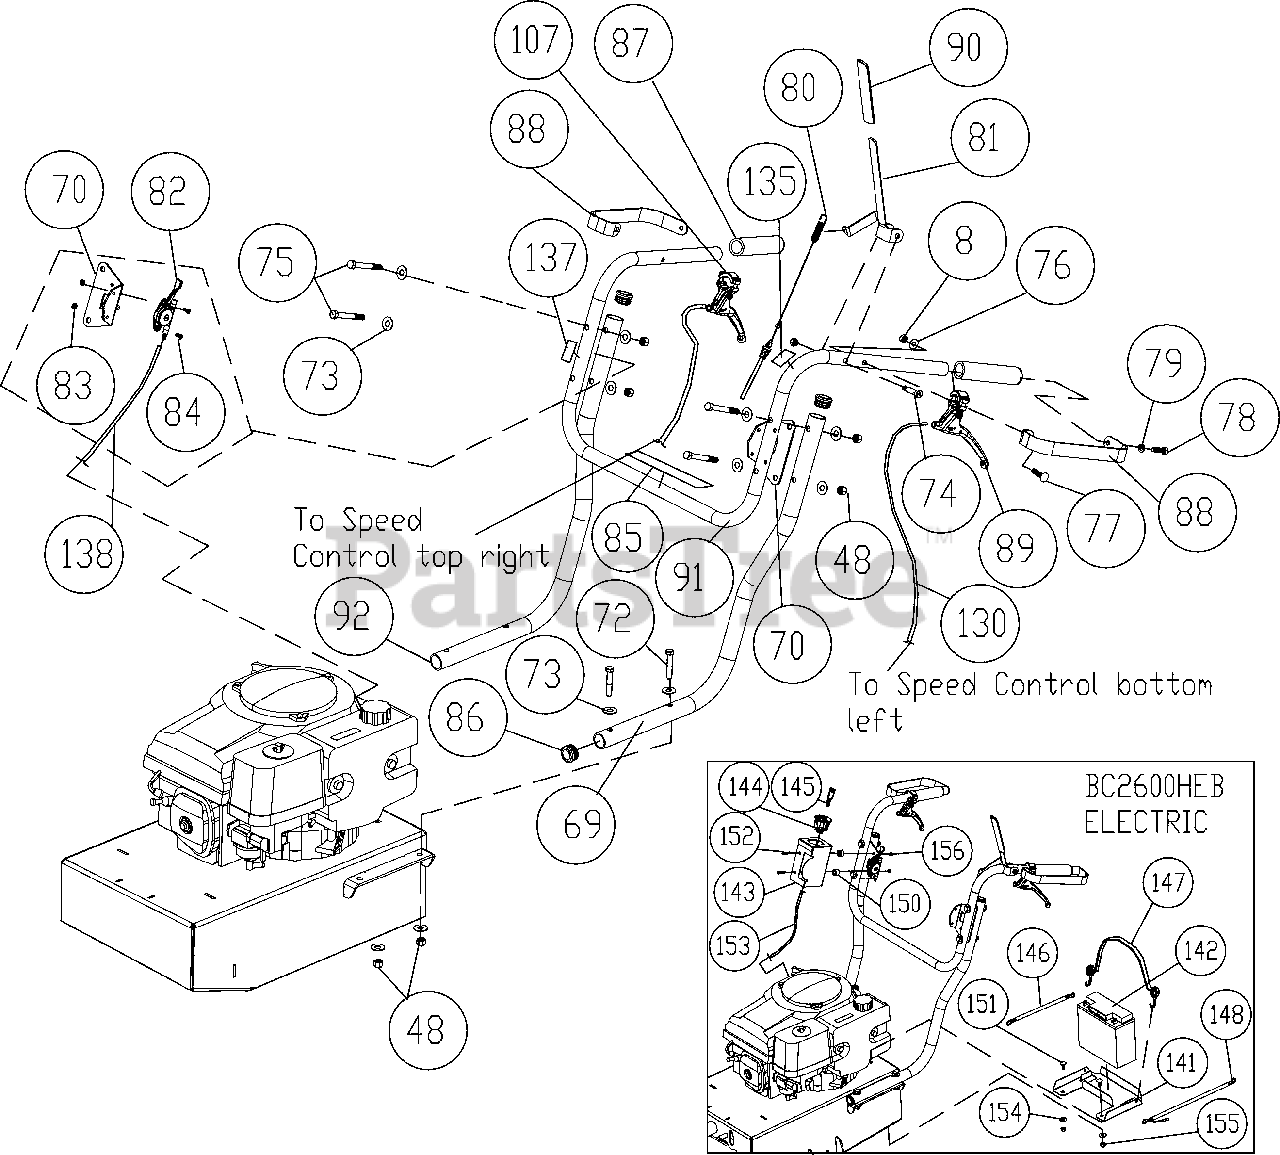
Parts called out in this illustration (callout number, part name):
8	NUT LOCK 5/16-18 ZP
48	NUT LOCK 3/8-16 HEX
69	HANDLE LOWER LEFT
70	BRACKET THROTTLE BC26
72	SCREWCAP 3/8”-16 X 2”
73	WASHER 3/8” FLAT
74	BOLT SHOULDER 3/8”-16 X 1 1/2”
75	SCREWCAP 3/8”-16 X 3” HCS ZP
76	WASHER 1/4” FLAT
77	BOLT CARRIAGE 5/16”-18 X 1 1/2” ZP
78	SCREWCAP 5/16”-18 X 1” ZP
79	WASHER LOCK 5/16” S/T MED
80	CABLE CLUTCH
81	LEVER CONTROL BLADE
82	CONTROL THROTTLE
83	NUT LOCK LT #10-24 HEX
84	SCREW MACHINE FLAT HD PHIL #10-24
85	LABEL DRIVE DIRECTION
86	PLUG TUBE INSERT 1.25” OD
87	GRIP HANDLE
88	GUARD HAND BC26
89	CONTROL MAGURA
90	GRIP LEVER 0.125” X 1” X 5” RED
91	HANDLE UPPER
92	HANDLE LOWER RIGHT
107	CABLE SPEED CONTROL RT
130	CABLE SPEED CONTROL LFT
135	LABEL BLADE ENGAGE
137	LABEL THROTTLE PULL START BC
138	CABLE THROTTLE
141	BATTERY BRACKET REAR BC
142	BATTERY 12V W/LABEL
143	BOX THROTTLE CONTROL
144	SWITCH IGNITION
145	DELTA KEY REPLACEMENT
146	CABLE BATTERY BLACK 10”
147	BUNGEE CORD BLACK 9” STRAP 79
148	CABLE BATTERY POSITIVE BC26
150	TUBE PIVOT IDLER VQ
151	BOLT CARRIAGE 5/16”-18 X 3/4” ZP
152	SCREWCAP 1/4”-20 X 1” HCS ZP
153	HARNESS WIRING BC26
154	WASHER 5/16” FLAT ZP
155	NUT LOCK 5/16”-18 HEX ZP
156	NUT LOCK 1/4”-20 HEX
